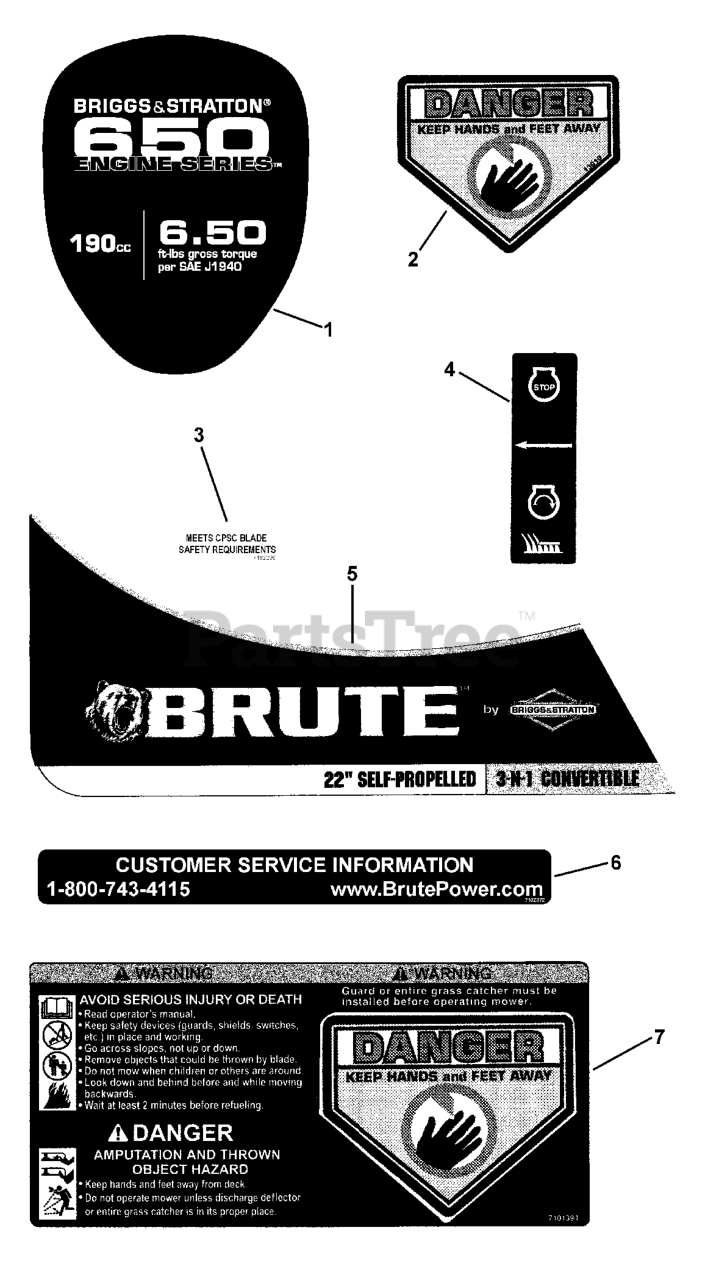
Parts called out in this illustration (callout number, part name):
1	DECAL, Engine, TP, Brute 650
2	DECAL, Danger, Cut Finger
3	DECAL, Blade CPSC
4	DECAL, OPC Bail International Symbol
5	DECAL, Deck Front 22"
6	DECAL, Customer Service, Brute
7	DECAL, Warning, Rear Discharge Door
